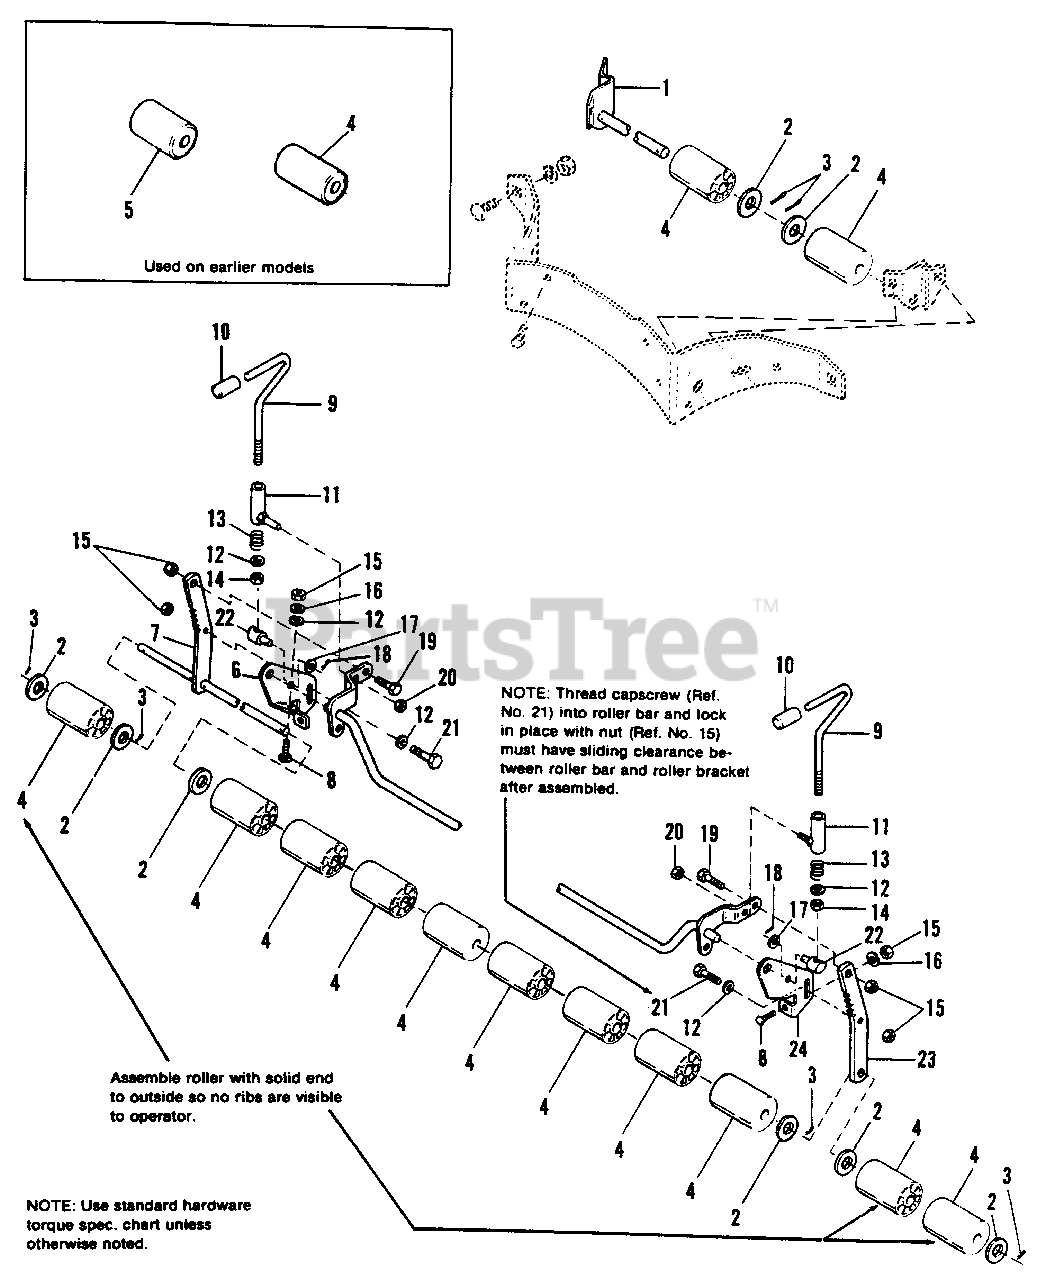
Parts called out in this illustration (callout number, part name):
1	BRACKET & SHAFT ASSY.
2	WASHER, Plain, 5/8
3	PIN, Cotter. 3/16 x 1
4	ROLLER, 2-1/2 x 3-15/16
5	ROLLER, 2-1/2 x 6-3/4
6	BRACKET, Roller, R.H.
7	SHAFT ASSY., Roller
8	CARRIAGE BOLT, 3/8-16 x 3/4
9	HANDLE, Adjusting
10	GRIP
11	SOCKET ASSY.
12	WASHER, Plain, 3/8
14	NUT, Hex, Jam, 3/8-16
15	NUT, Hex, Full, 3/8-16
16	LOCKWASHER, 3/8
17	WASHER, 3/8
18	PIN, Cotter, 3/32 x 3/4
19	CAPSCREW, Hex Hd., 3/8-16 x 1
20	LOCKNUT, Hex, Full, 3/8-16
21	CAPSCREW, Hex Hd., 3/8-16 x 1
23	BAR, Roller
24	BRACKET, Roller, L.H.
